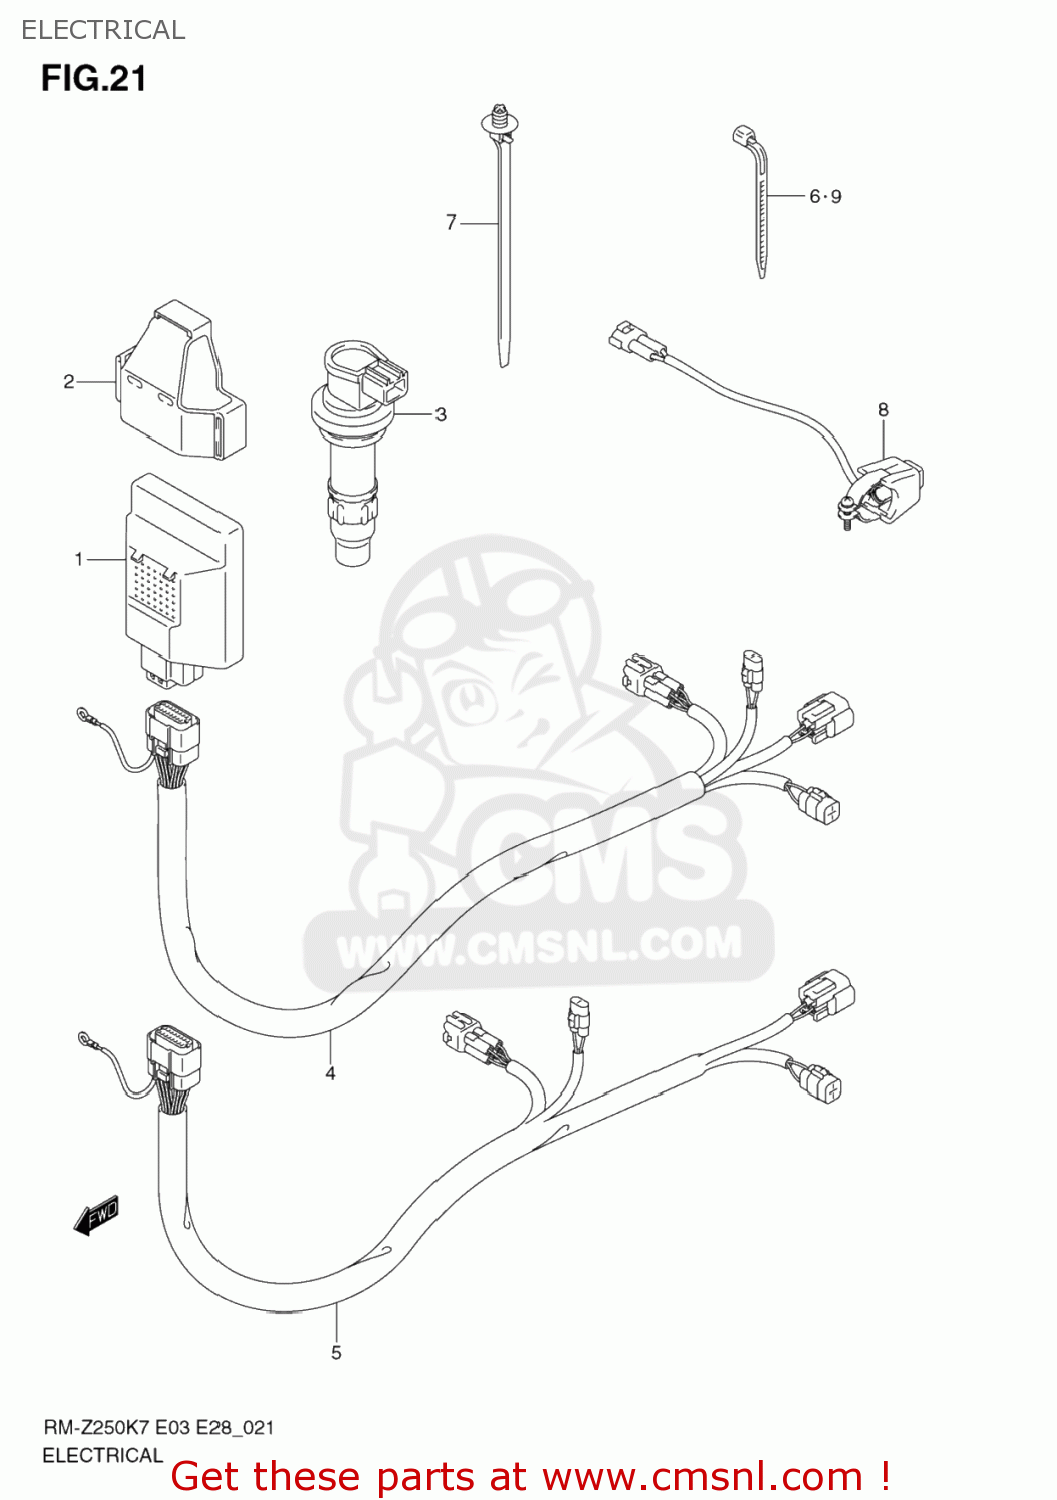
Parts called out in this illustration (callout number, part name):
1	CDI UNIT
2	CUSHION,CDI UNIT
3	COIL ASSY,IGNITION
4	HARNESS,WIRING
5	HARNESS,WIRING
6	CLAMP(L:95)
7	CLAMP(L:154)
8	SWITCH ASSY,ENGINE STOP
9	CLAMP(L:95)
